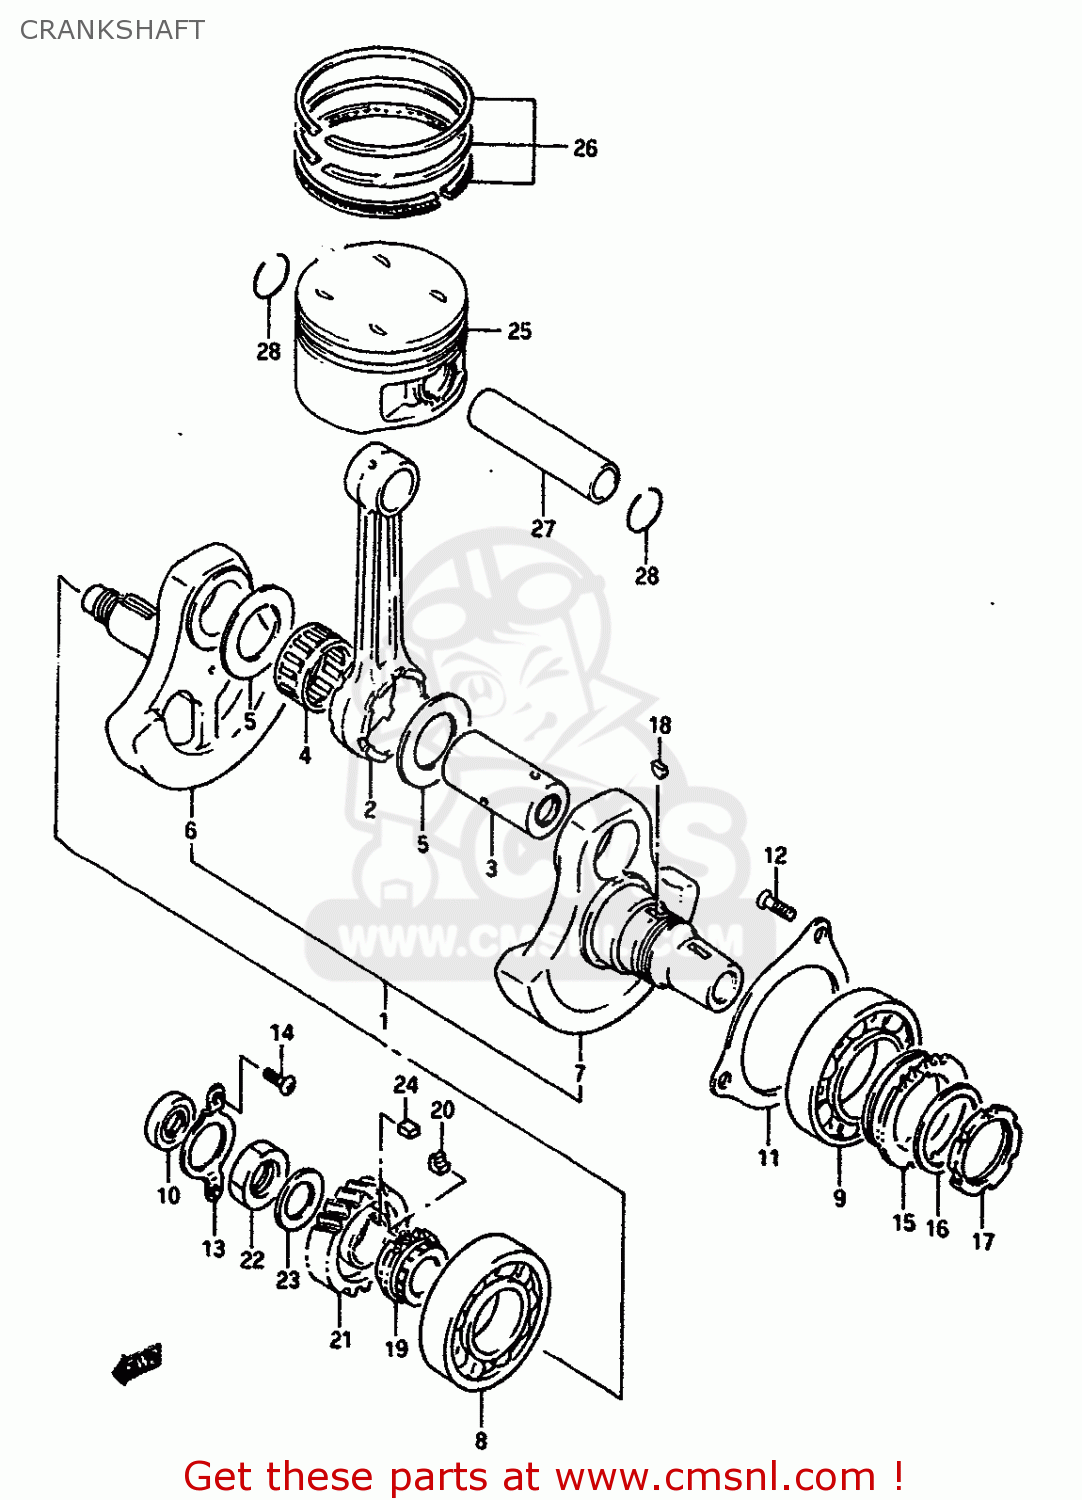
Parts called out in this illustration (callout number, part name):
1	CRANKSHAFT ASSY
2	ROD,CONNECTING
3	PIN,CRANK
4	BEARING
5	WASHER(35X55X1)
6	CRANKSHAFT,RIGHT
7	CRANKSHAFT,LEFT
8	BEARING(35X80X21)
9	BEARING
10	SEAL,OIL(16X30X6)
11	RETAINER,CRANKSHAFT BEARING,L
12	SCREW
13	RETAINER,CRANKSHAFT BEARING,R
14	SCREW
15	SPROCKET,BALANCER DRIVE
16	WASHER
17	NUT,FLYWHEEL
18	KEY
19	SPROCKET,CAM CHAIN DRIVE
20	KEY,SPROCKET
21	GEAR,PRIMARY DRIVE
22	NUT (20MM)
23	WASHER
24	KEY
25	PISTON
26	RING SET,PISTON
27	PIN,PISTON
28	CIRCLIP
